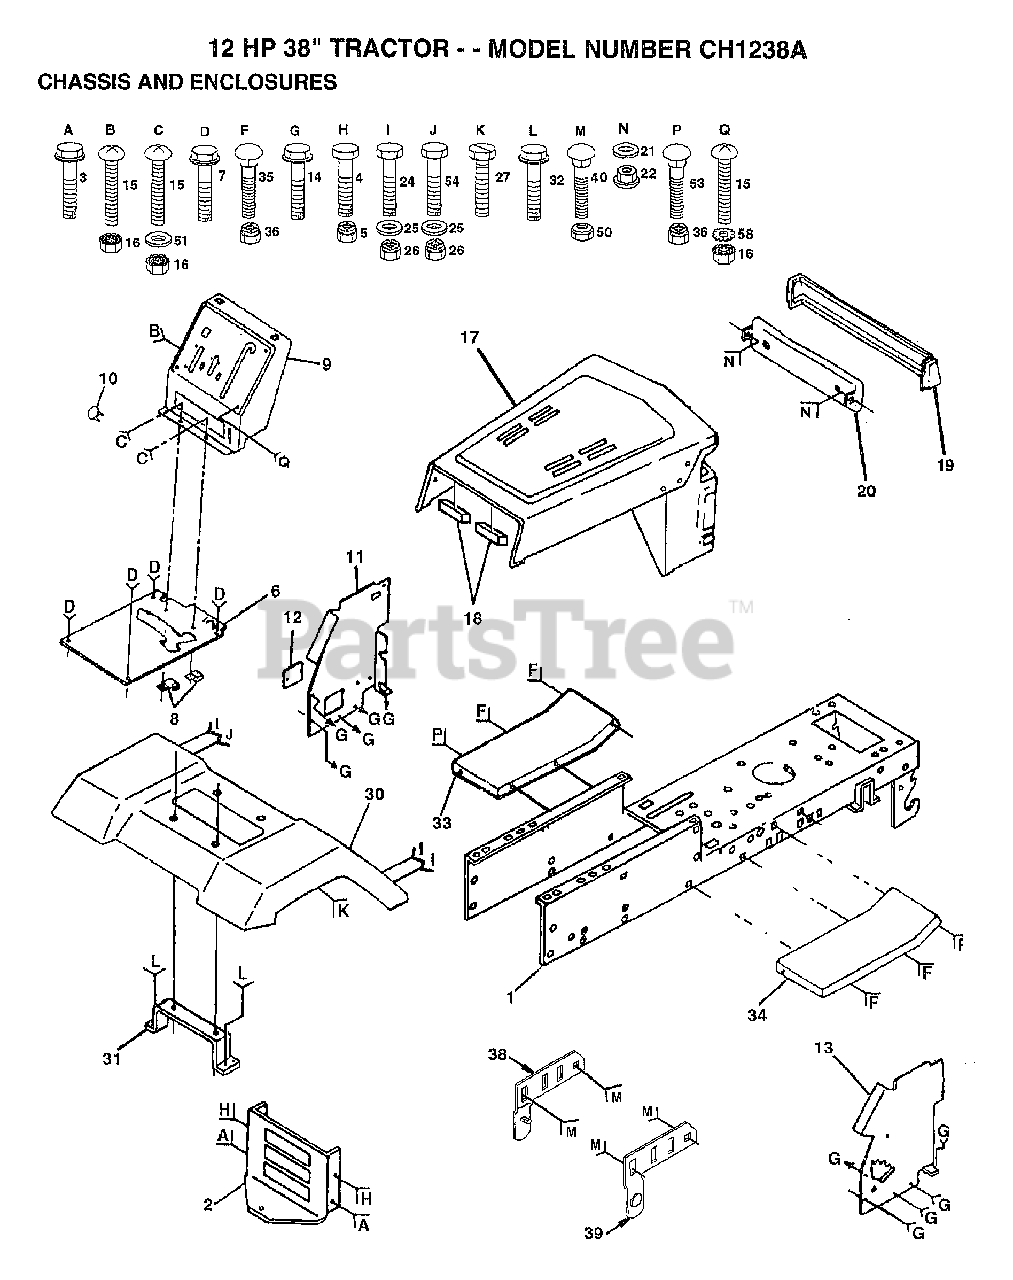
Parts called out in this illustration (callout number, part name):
3	SCREW
7	SCREW LT
8	CLIP T
10	PLUG BUTTON T
11	PANEL DASH LH
12	COVER ACCESS
14	SCREW LT
15	SCREW
17	HOOD/GRILL ASM
21	WASHER PM
22	PAL NUT LT
25	WASHER
27	SCREW LT
30	FENDER
31	BRKT FENDER
32	SCREW
33	FOOTREST LH
34	FOOTREST RH
35	BOLT
38	BRKT ASM PIVOT LH
39	BRKT ASM PIVOT RH
50	NUT
51	WASHER
58	LOCKWASHER
